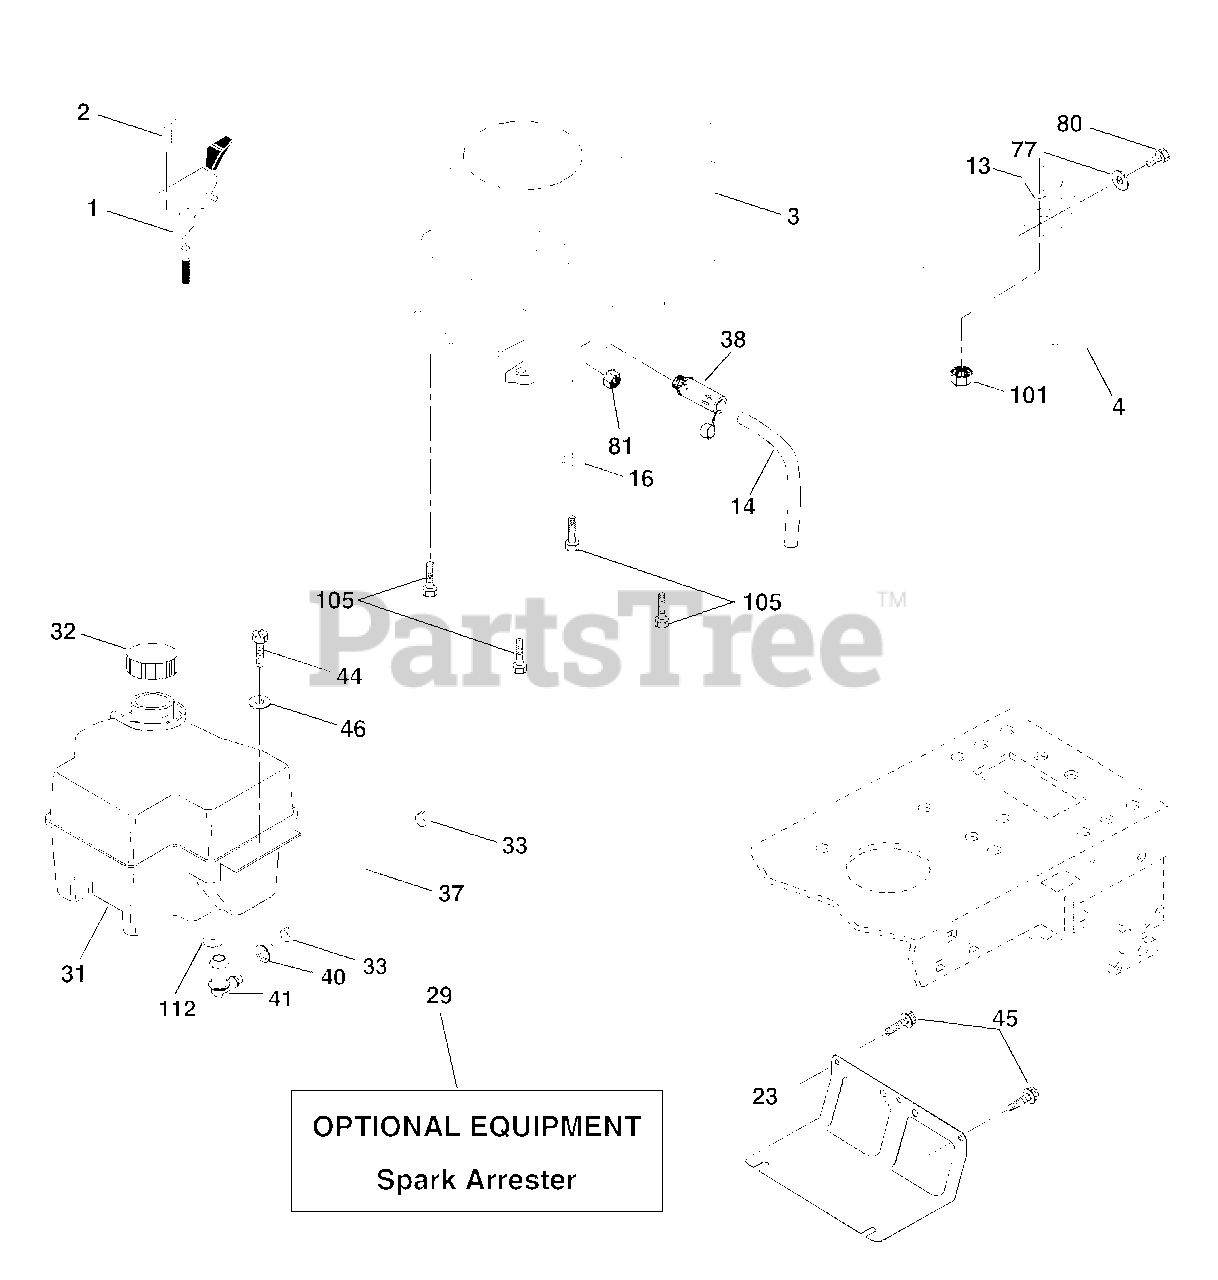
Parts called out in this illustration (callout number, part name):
1	Control Th/ch Flag Dom.
2	Screw Hex Thd Cut 1/4-20x1/2
14	Tube Drain Oil Easy
16	Washer Lock Ext Tooth 3/8
23	Shield BRN/DBR Guard
29	Kit Spark Arrestor (Flat Scrn)
32	Cap Asm Fuel W/sym Vented
33	Clamp Hose Black
37	Line Fuel
38	Plug Drain Oil Easy
40	Bushing Snap Nyl Black Fuel Line
41	Stem Tank Fuel
44	Screw Hex Wsh Thdrol 1/4-20 x 3/4
45	Screw Hex Wsh Thdrol 3/8-16 x 3/4
46	Washer 9/32 x 7/8 x 16 Ga.
62	Washer Lock Hvy Hlcl Spr. 5/16
77	Washer 5/16 x 3/4 x 16 Ga.
80	Bolt Hex 5/16-18unc x 1/2
81	Nut Keps Hex 1/4-20 Unc
101	Nut Flange M8-1.25
105	Screw 3/8-16 x 1
112	Bushing
